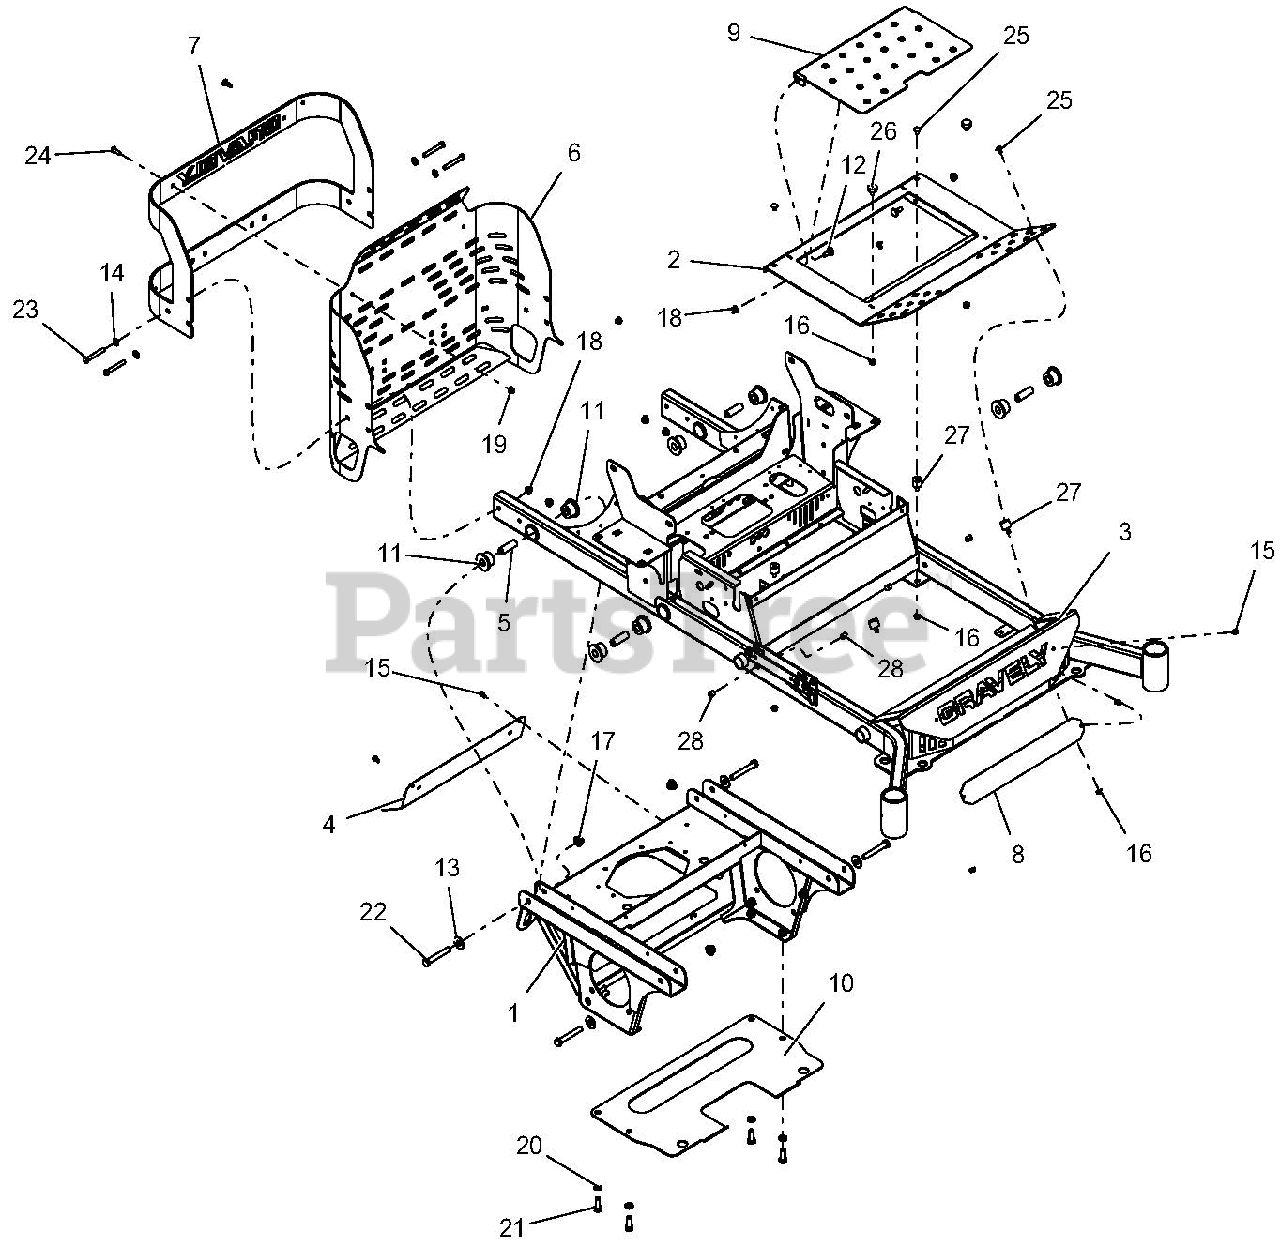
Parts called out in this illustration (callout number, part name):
1	WLDT, 200 PT AXLE/ENGINE FRAME
2	FOOTPLATE WLDMT W/SAFETY DECAL
3	52-66" MAIN FRAME W/SAFETY DECALS
4	SHIELD, MUFFLER HEAT
5	SPCR, .50 X .75 X 2.23 YZ
6	WLDMT, PT200 REAR BUMPER
7	REAR BUMPER W/SAFETY DECALS-GAS
8	PLATE, BUMPER LOGO BACKING-BLACK
9	PANEL, INSPECTION
10	PLATE-TRANSMISSION SKID-RED
11	BSHG, FLANGE .750 X 1.510 X 1.130 X 2.000
12	BLT, SHLDR EP .38-16X.30 HEX YZ
13	WSHR-FL-STL.563X1.38X.109YWZC
14	WSHR-FL-STL.406X.812X.065 YWZ
15	SCR-TAP .25-20X.50 HWH TR YWZ
16	@NUT-SPNLK-FLG .312-18 YWZC
17	NUT-LK-NYL-FLG .50-13 YWZC
18	NUT-LK-NYL-FLG .38-16 YWZC
19	NUT-LK-NYL-FLG .31-18 YWZC
20	WSHR-LK .50X.125 REG YWZC
21	BLT-HEX .50-13X1.25 GR5 YWZC
22	BLT-HEX .50-13X3.50 GR5 YWZC
23	BLT-HEX .38-16X2.75 GR5 YWZC
24	BLT-RDHDSQSHNK .31-18X1.00 G5YWZC
25	BLT-RDHDSQNK .31-18X.50 G5 YWZC
26	BUMPER, RUBBER
27	BUMPER, STUD MOUNTED W/FEMALE INSERT
28	PLUG, HOLE .500
